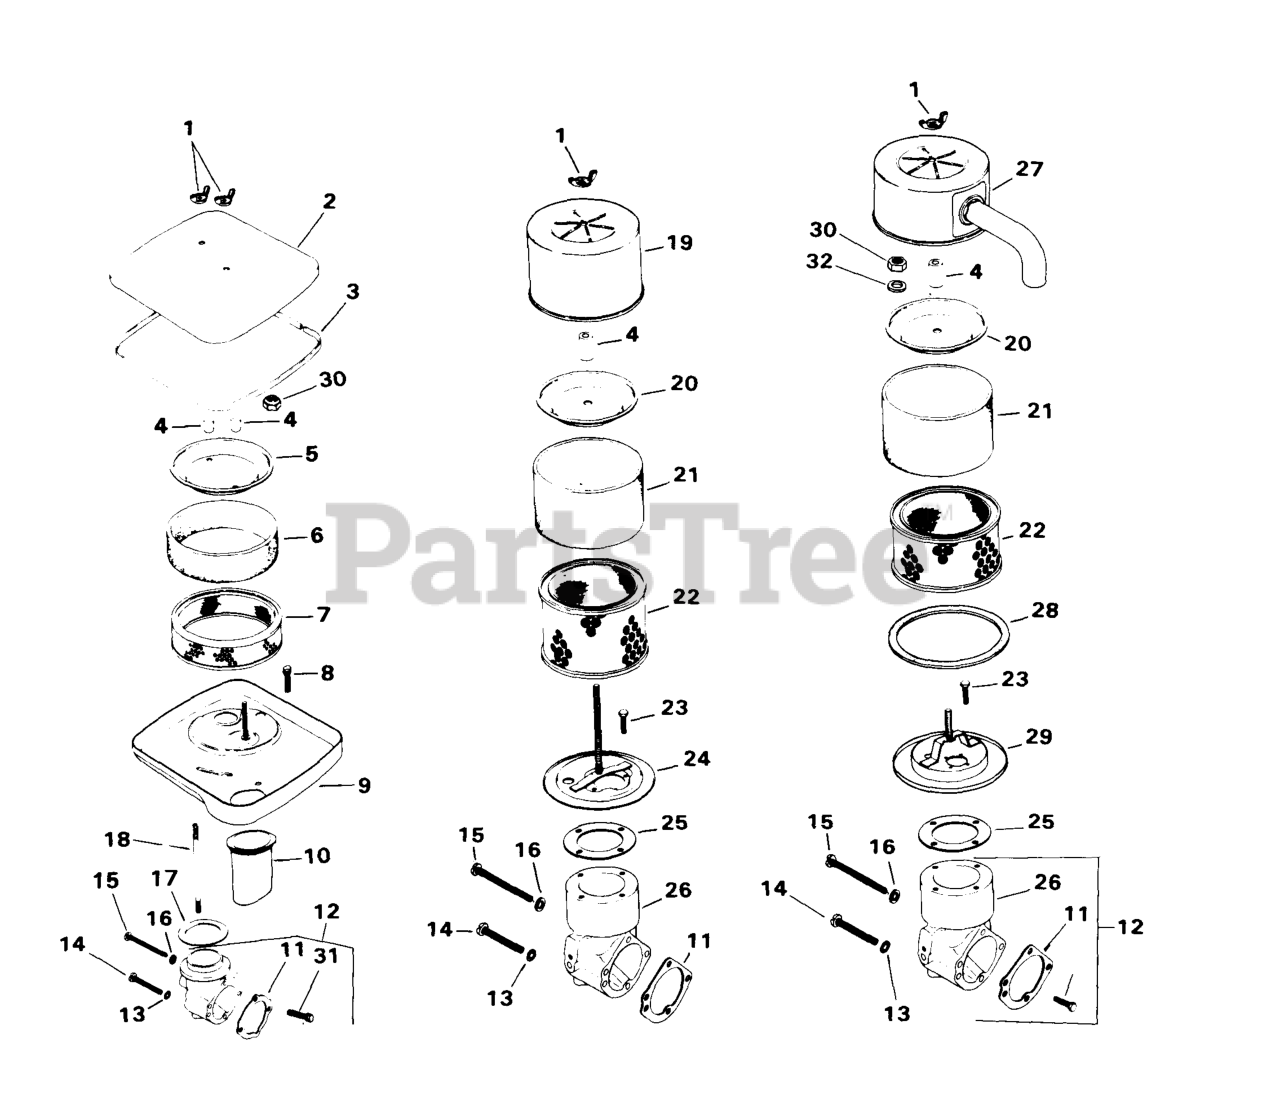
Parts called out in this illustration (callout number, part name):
1	Wing Nut 1/4-20
2	Cover, Air Cleaner - Square
3	Seal, Air Cleaner Cover
4	Seal, Element Cover
5	Cover, Air Cleaner Element
6	Precleaner
7	Element, Air Cleaner
8	Screw, Hex. Wash. Hd. 1/4-20x7/16"
9	Base, Air Cleaner
10	Tube, Air Cleaner
11	Gasket, Air Cleaner Elbow
12	Kit, Air Intake Elbow
13	Washer, I.T. #10
14	Screw, Sltd. Pan Hd. 10-32x1-1/2"
15	Screw, Sltd. Pan Hd. 10-32x2-1/4"
16	Washer, Plain #10
17	Gasket, Air Cleaner
18	Stud 1/4-20x4-3/4"
31	Screw, Hex. Wash. Hd. 1/4-20x3/4"
